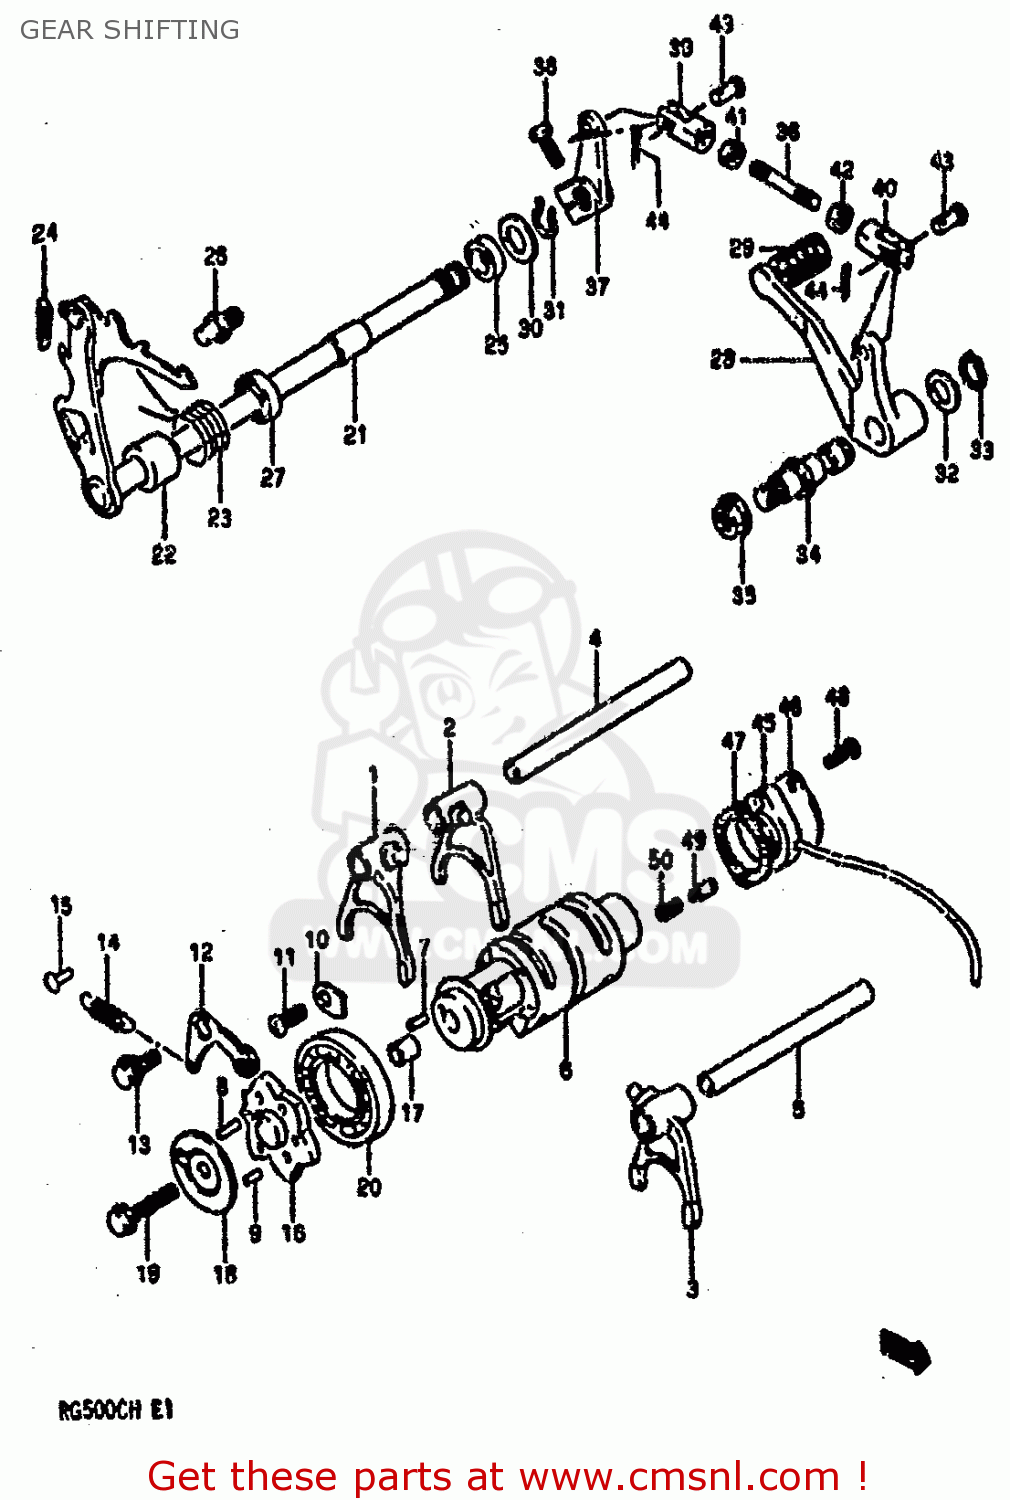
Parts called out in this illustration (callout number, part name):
1	FORK,NO.1
2	FORK,GEAR SHIFT NO.2
3	FORK,NO.3
4	SHAFT,GEAR NO1
5	SHAFT,FORK NO.2
6	CAN
7	PIN
8	ROLLER(4X13.8)
9	PIN(4X11.8)
10	RETAINER
11	SCREW 6X12
12	STOPPER,CAM
13	BOLT
14	SPRING
15	RIVET
16	PLATE,SHIFT CAM STOPPER
17	PIN
18	RETAINER
19	BOLT
20	BEARING
21	SHAFT,GEAR SHIFTING
22	SPACER(12X20X15.3)
23	SPRING
24	SPRING
25	GUIDE,SHIFT SHAFT
26	STOPPER,GEAR SHIFT CAM
27	OIL SEAL
28	LEVER ASSY,GEAR SHIFTING
29	RUBBER,GEAR SHIFT PEDAL
30	WASHER (12.5X24X1.6)
31	SPRING,RETAINER
32	WASHER(12.5X20X1)
33	CIRCLIP
34	SHAFT,GEAR SHIFT LEVER
35	NUT
36	ROD,GEAR SHIFT
37	SCHAKELARM
38	BOLT
39	JOINT,GEAR SHF
40	JOINT,GEAR SHIFTING LINK
41	NUT
42	NUT
43	PIN,GEAR SHIFT LINK
44	CLIP
45	BODY,SWITCH
46	PROTECTOR,SWITCH
47	GASKET (MCA)
48	SCREW
49	PIN(5X15.5)
50	SPRING
